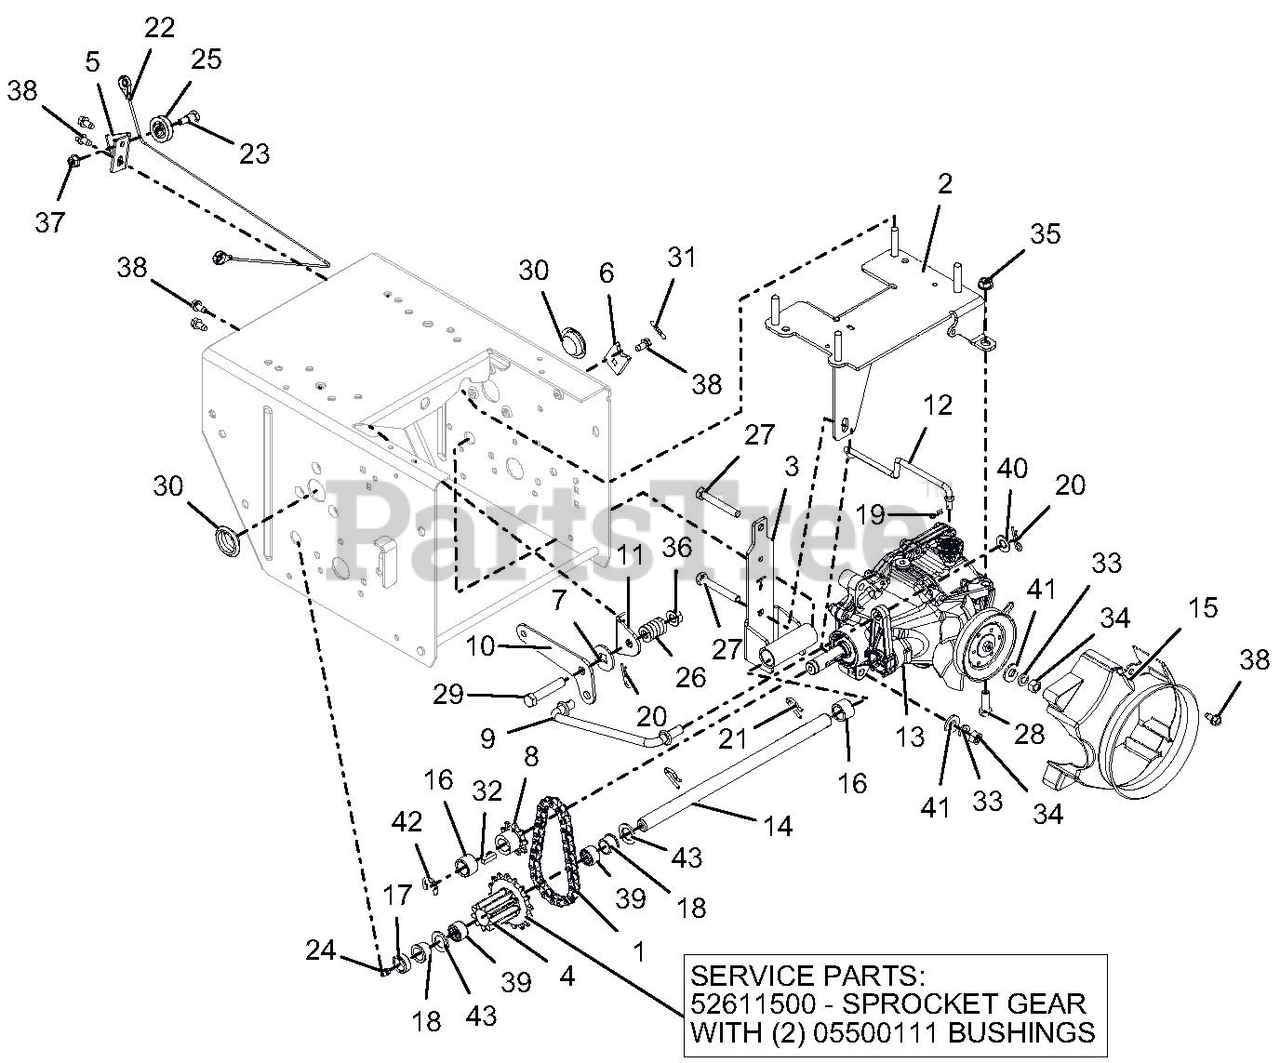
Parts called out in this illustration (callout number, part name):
1	CHAIN-ROLLER #41X26 PITCHES
2	BRACKET, HYDROSTATIC TRANS XLG
3	TRANS MOUNT, TENSIONING, TRACK
4	PINION & SPROCKET (16T & 9T)
4	PINION & SPROCKET W/BEARINGS
4	BSHG-FLG .625X.750X.500X.875
5	BRACKET, CABLE PULLEY
6	TAB, ANTI ROTATION
7	FRICTION WASHER
8	SPROCKET, PINION 9T W/KEY
9	ROD, HYDRO TRANS SHIFT
10	PIVOT, HYDRO TRANS SHIFT
11	BRACKET, HYDRO SHIFT PIVOT
12	ROD, HYDRO BYPASS
13	TRANSMISSION, HYDROSTATIC
14	SHAFT, PINION - HARDENED
15	SHROUD, HYDROGEAR RT-310
16	SPACER, .635X.880X.611
17	BSHG-SLV, .635X.880X.305
18	BSHG-FLG .625X.750X.500X.875
19	PIN-HAIR INT .06X.18X.77
20	PIN-HAIR INT .08X.18X1.18 YWZC
21	PIN, SPRING CLIP
22	CABLE, TRACTION, HYDRO PRO
23	BOLT, SHLDR-.375X.375X.25-20
24	ZERK,FITTING .25X.125 DRIVE IN
25	PULLEY, CABLE
26	SG-COMP .187X.56X1.62
27	@BLT-HEX .31-18X2.25 GR5 YWZC
28	@BLT-HEX .31-18X1.00 GR5 YWZC
29	@BLT-HEX .38-16X2.00 GR5 YWZC
30	PLUG, HOLE - 1.125"
31	@PIN-GRV .125X1.00 TP E ALLOY
32	KEY-SQ .188X.75X.188
33	WSHR-LK .312X.097 HVY YWZC
34	@NUT-HEX .31-18 YWZC
35	@NUT-LK-TOP-FLG .31-18 YWZC
36	@NUT-LK-TOP-FLG .38-16 YWZC
37	@NUT-LK-TOP-FLG .25-20 YWZC
38	SCR-TAP .25-20X.50 HWH TR YWZ
39	BRG-NEEDLE .625X.812X.50
40	@WSHR-FL-STL.406X.812X.065 YWZ
41	@WSHR-FL-STL.38X.875X.083 YWZC
42	RG-RTNG-EXT .625X.042
43	WSHR-FL-STL .630X1.005X.062 YZ
